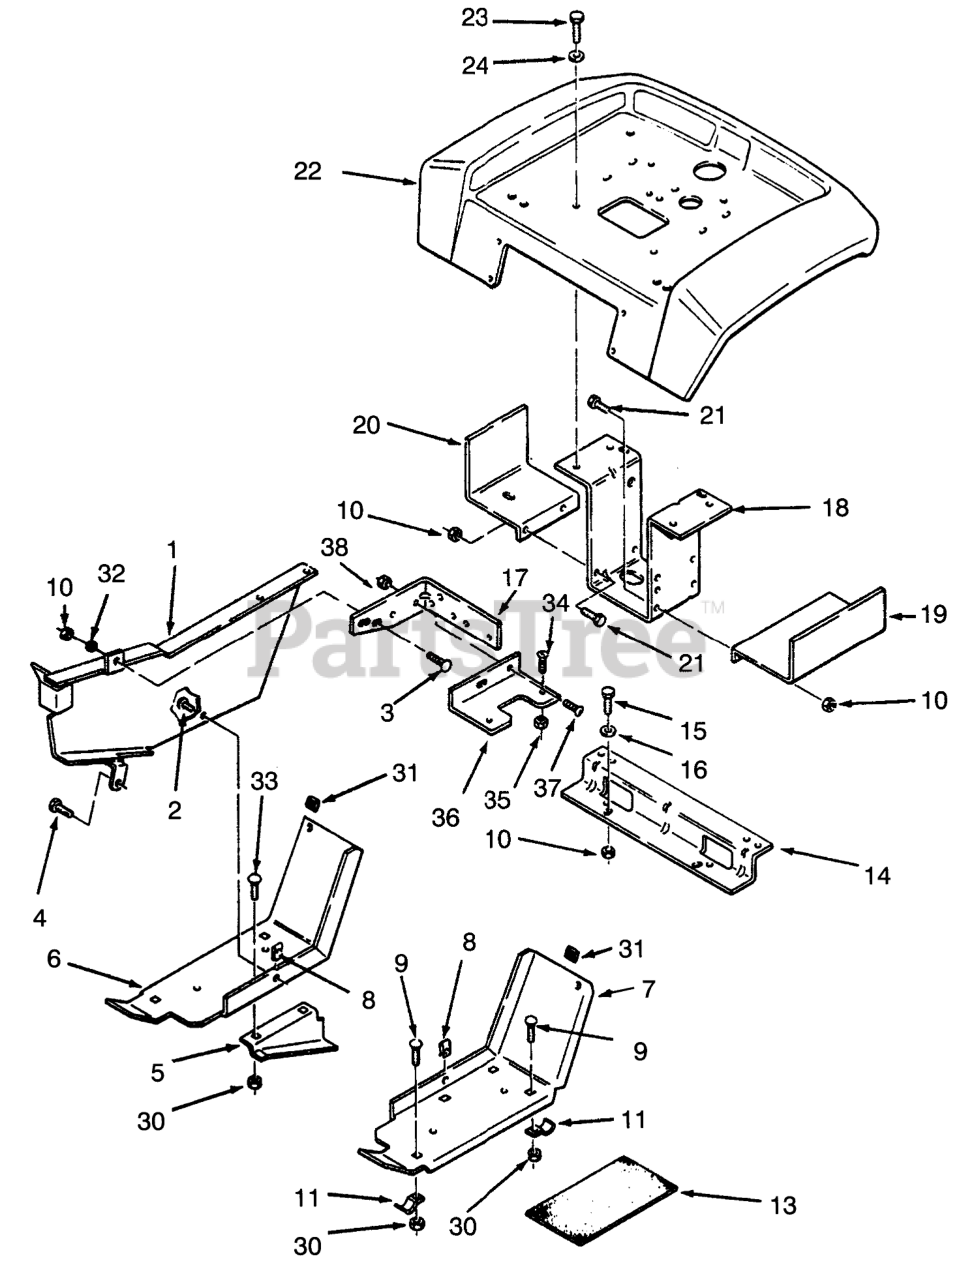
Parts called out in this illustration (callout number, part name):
1	Belt Guard
2	Screw
3	BOLT-CARR
4	SCREW
5	GUID-LOWER BLTR
6	Footrest-RH
7	FOOTREST LH R
9	BOLT-CARR
10	NUT-LOCK, NI
11	BRACKET
13	PAD FOOTREST
14	BRACKET-FENDER B
15	SCREW-HH
16	WASHER-PLAIN
17	BRACKET-BELTB
18	Bracket-Fender
19	Fuel Tank Support LH
20	Support-FueITank RH
21	SCREW-HH
22	Fender
23	SCREW
24	WASHER 5/16 SAE
30	NUT-LOCK, NI
31	BUMPER SJ5514 BLACK
32	NUT-PUSH
33	BOLT-CARR 5/16 SN
35	Nut
36	FUSE HOLDERB
37	SCREW-HH
38	NUT-LOCK, NI
